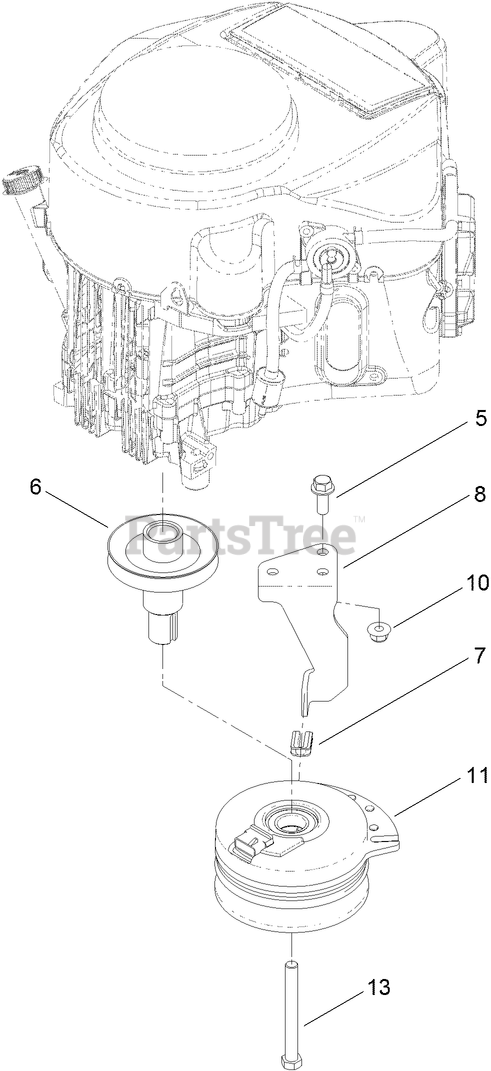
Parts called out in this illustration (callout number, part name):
5	SCREW-HHF
6	PULLEY-ENGINE
7	ISOLATOR-CLUTCH
8	STOP-CLUTCH (NARROW)
10	NUT-HF, NI
11	CLUTCH-ELECTRIC
13	SCREW-HH
